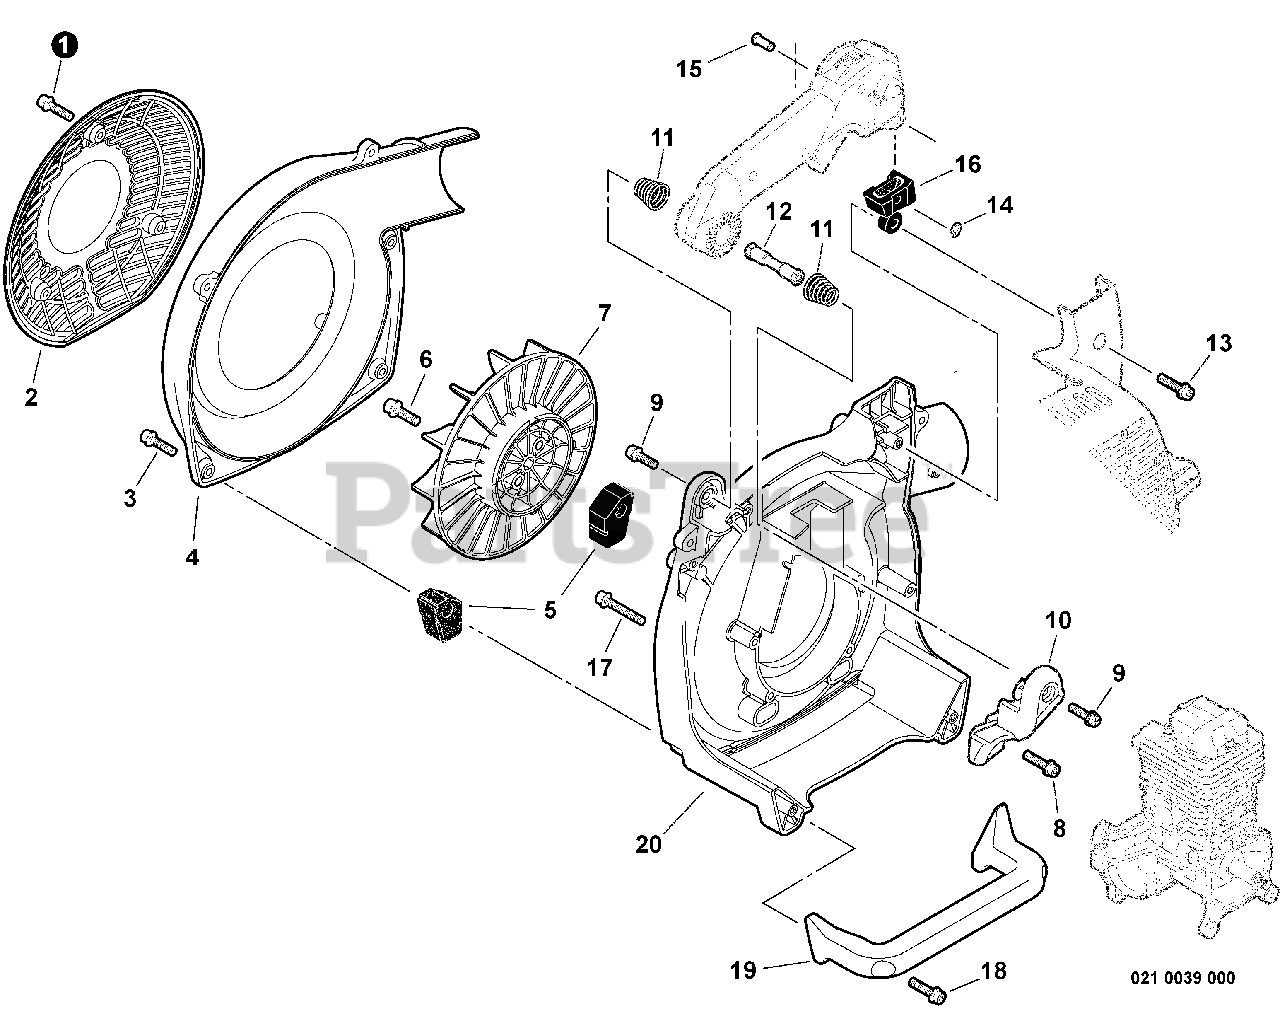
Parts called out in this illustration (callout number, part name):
1	BOLT M5×20
2	COVER, INTAKE
3	BOLT M5×20
4	COVER, FAN
5	CUSHION
6	BOLT M6×20
7	FAN Ø176.5
8	SCREW 5×20
9	SCREW, ADHESIVE M5×16
10	MOUNT, HANDLE
11	SPRING, COIL Ø18ר14
12	NUT, HANDLE 5
13	BOLT M5×20
14	RING, SNAP 8 MM
15	PIN, LOCK
16	CUSHION, AV
17	BOLT M5×40
18	BOLT M5×20
19	HANDLE, SIDE
20	CASE, FAN
